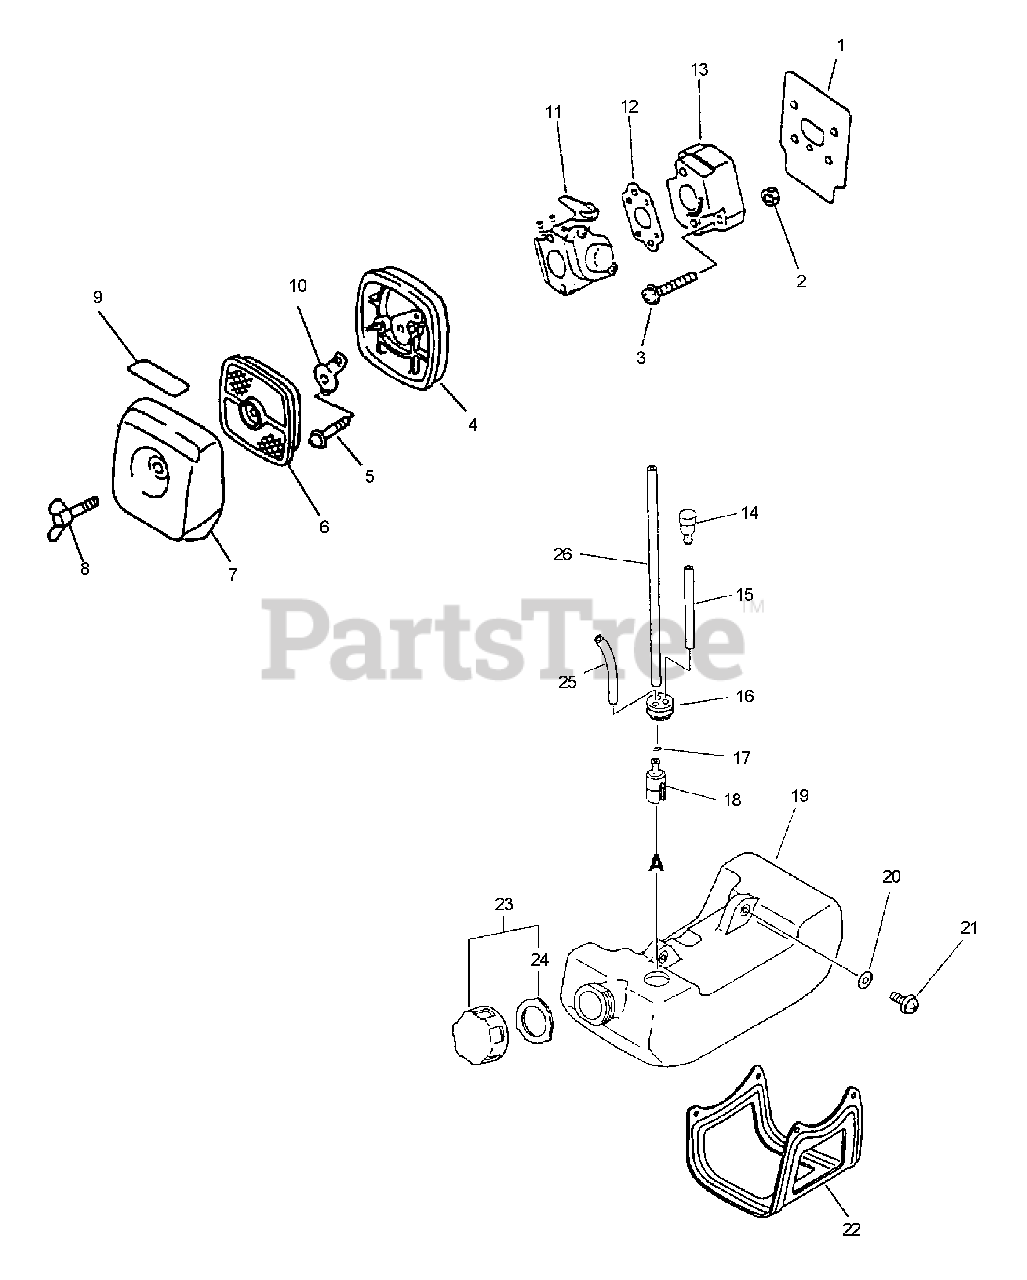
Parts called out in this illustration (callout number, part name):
1	SHIELD, INTAKE
3	SCREW - 5X20
4	AIR FILTER CASE ASSY
5	SCREW - 5X65
6	FILTER, AIR - SINGLE LAYER
7	COVER, AIR FILTER - BLACK
8	THUMBSCREW
9	LABEL - CHOKE
10	PLATE, PREVENT
11	CARBURETOR C1U-K52
12	GASKET, INTAKE
13	INSULATOR, INTAKE
14	VENT, FUEL TANK
15	PIPE - 3X5X70 -- BLACK
16	GROMMET
17	CLIP - 6
18	FILTER, FUEL
19	FUEL TANK ASSY
20	WASHER - 5
21	SCREW - 5X16
22	GUARD, FUEL TANK
23	CAP ASSY
24	GASKET, CAP
25	PIPE - 3X6X90 -- CLEAR
26	PIPE - 3X5X180 -- BLACK
